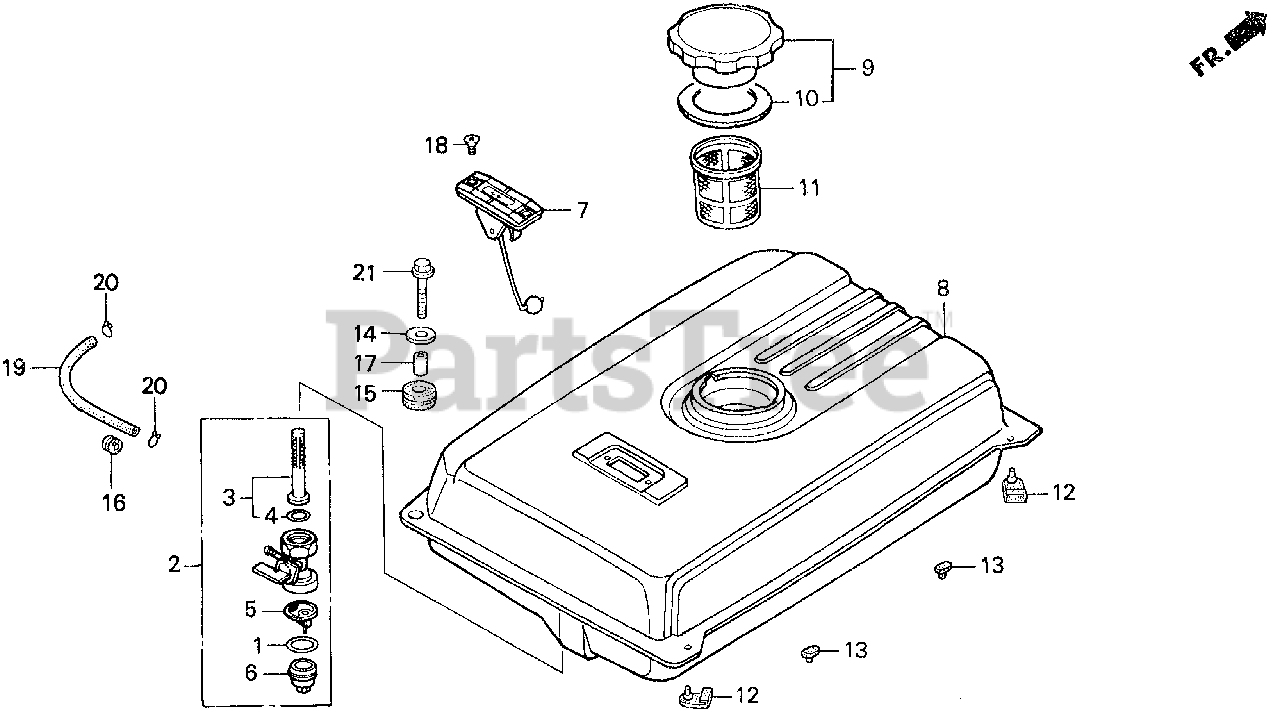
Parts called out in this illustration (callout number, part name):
1	GASKET, FUEL STRAINER CUP
2	PETCOCK ASSY.
3	SCREEN, FUEL STRAINER
4	O-RING (9X1.3)
5	FILTER, CUP
6	CUP, FUEL STRAINER
16	RUBBER, FUEL TUBE
19	BULK HOSE, FUEL (4.5X3000) (4.5X210)
20	CLIP, TUBE (B8)
